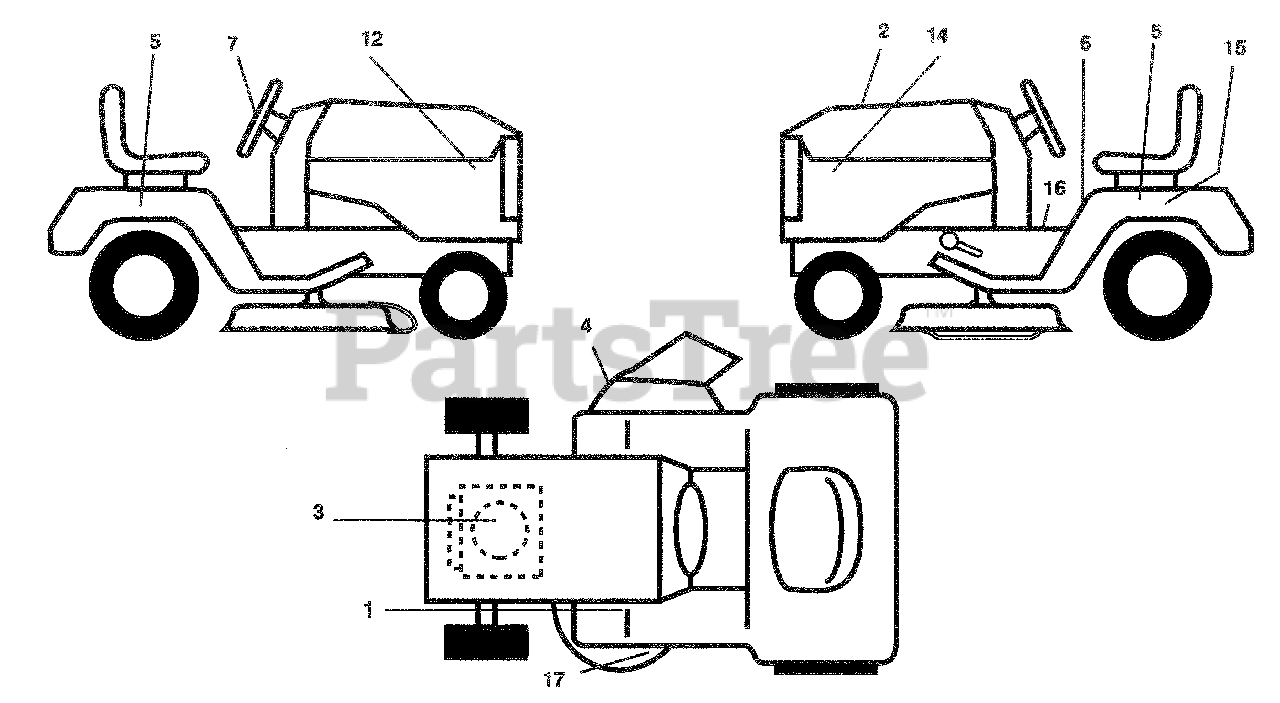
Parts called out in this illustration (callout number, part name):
1	Decal, Clutch/Brake Eng/Fr
2	Decal, Replacement
3	Decal, Engine HP
4	Decal Warning
5	Decal 5-Speed
6	Decal, Fender Danger English
7	Decal Ins Str Wh
12	Decal, Hood RH
14	Decal, Hood LH
15	Decal, Caution, Battery
16	Decal, Oper Sdl P/L Gear Dr Eng
17	Decal, V-Belt Sch.
17	Decal, Handle Lft Height Adj.
17	Manual, Operator's (E&F)
17	Manual, Parts (E&F)
